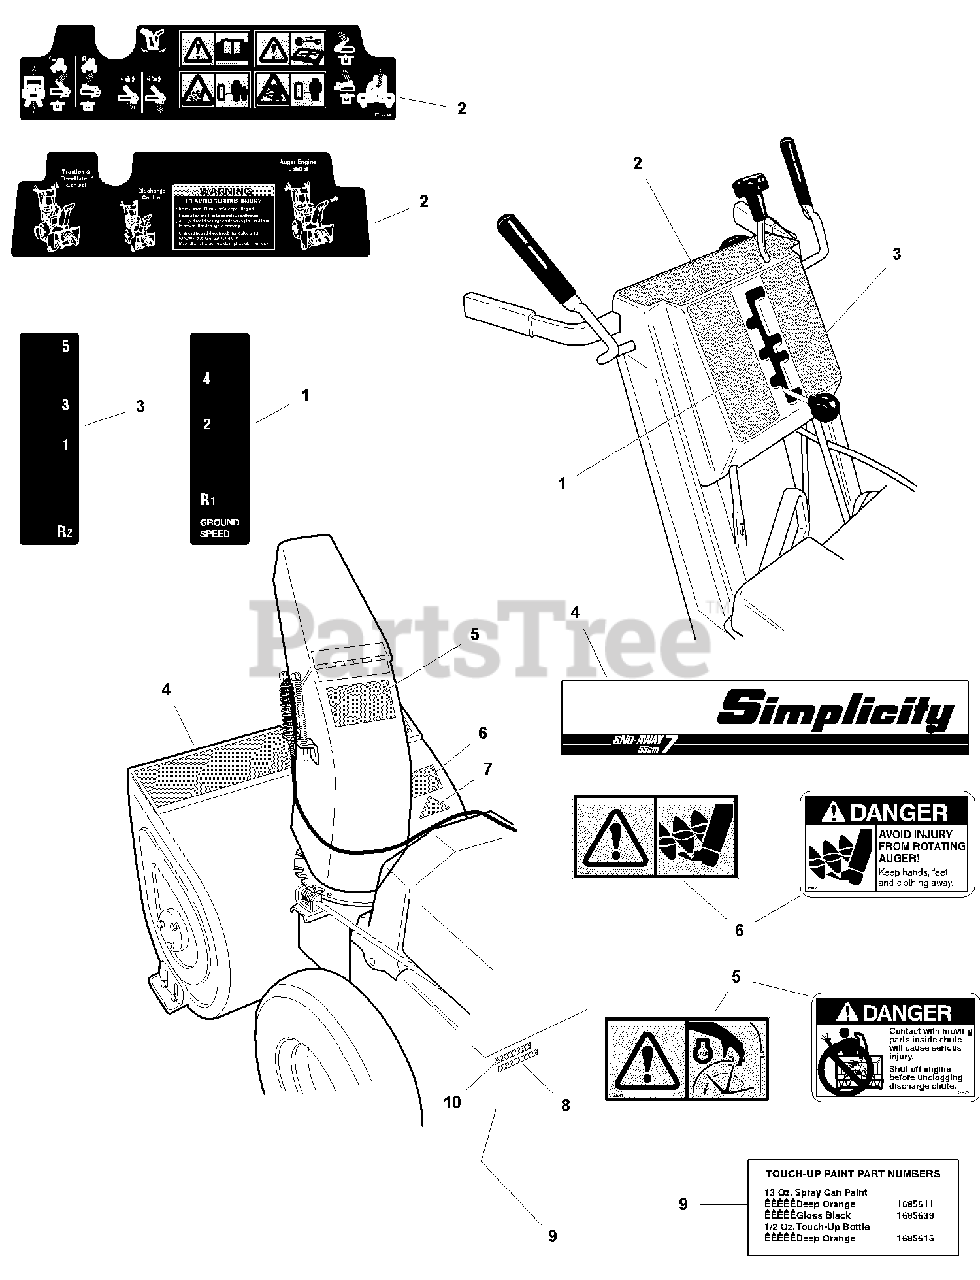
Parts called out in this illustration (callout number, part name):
1	DECAL, Shift Pattern, RH
2	DECAL, Dash
2	DECAL, Dash (Export)
3	DECAL, Shift Pattern, LH
4	DECAL, Stripe, 860
4	DECAL, Stripe, 970
4	DECAL, Stripe, 1180
5	DECAL, Discharge Chute Danger (Export)
5	DECAL, Discharge Chute Warning
6	DECAL, Auger Danger
6	DECAL, Auger Danger (Export)
7	DECAL, OPEI (Not Serviced)
8	DECAL, Decibel (Export)
8	DECAL, Patent
9	DECAL, Touch Up Paint Deep Orange
10	I.D. Tag (Not Serviced)
